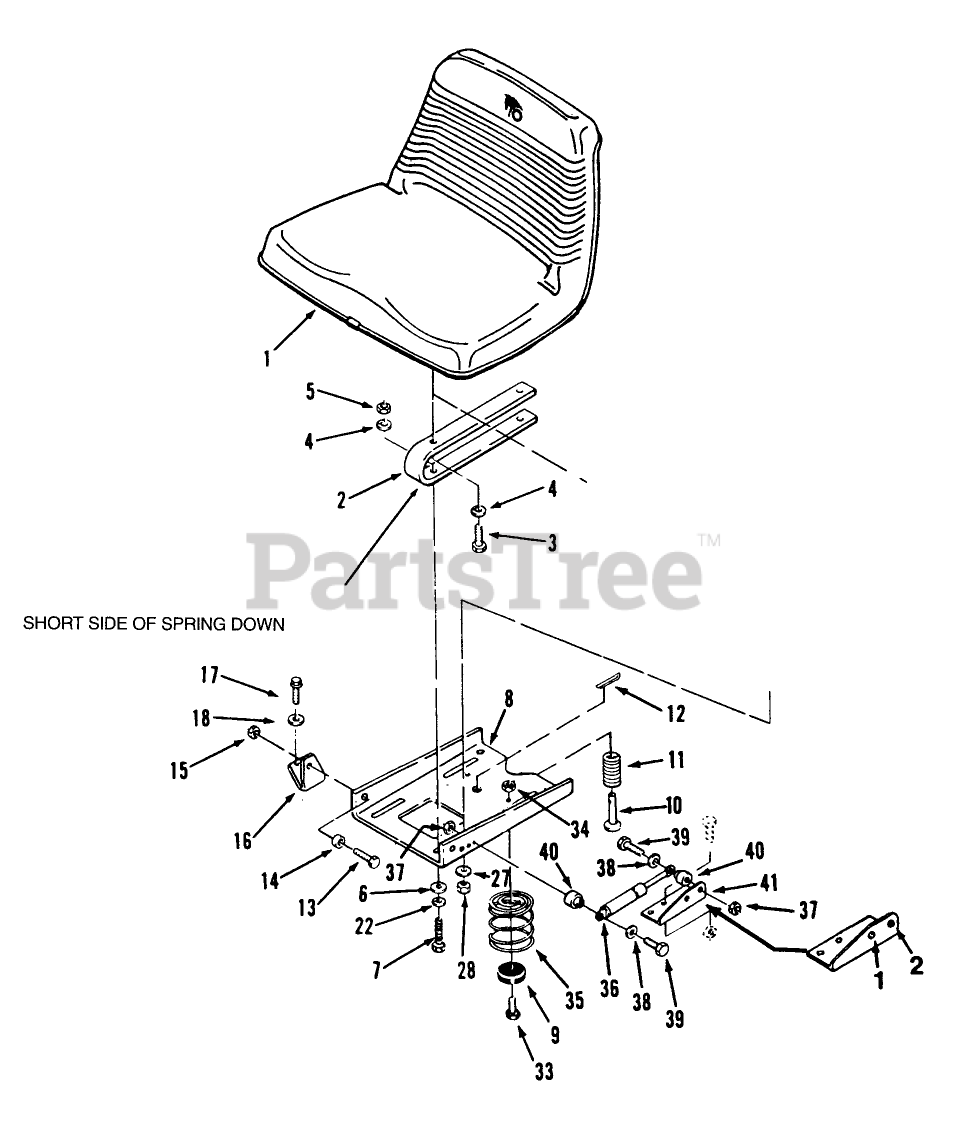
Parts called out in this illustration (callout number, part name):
3	SCREW
6	WASHER 5/16 SAE
9	BUMPER
11	SPRING-SEAT SWITCH
14	BUSHING
16	BRACKET-PIVOT R.H *B (NS)
36	GAS SPRING
40	SPACER
41	BRACKET-CYLINDER *R
